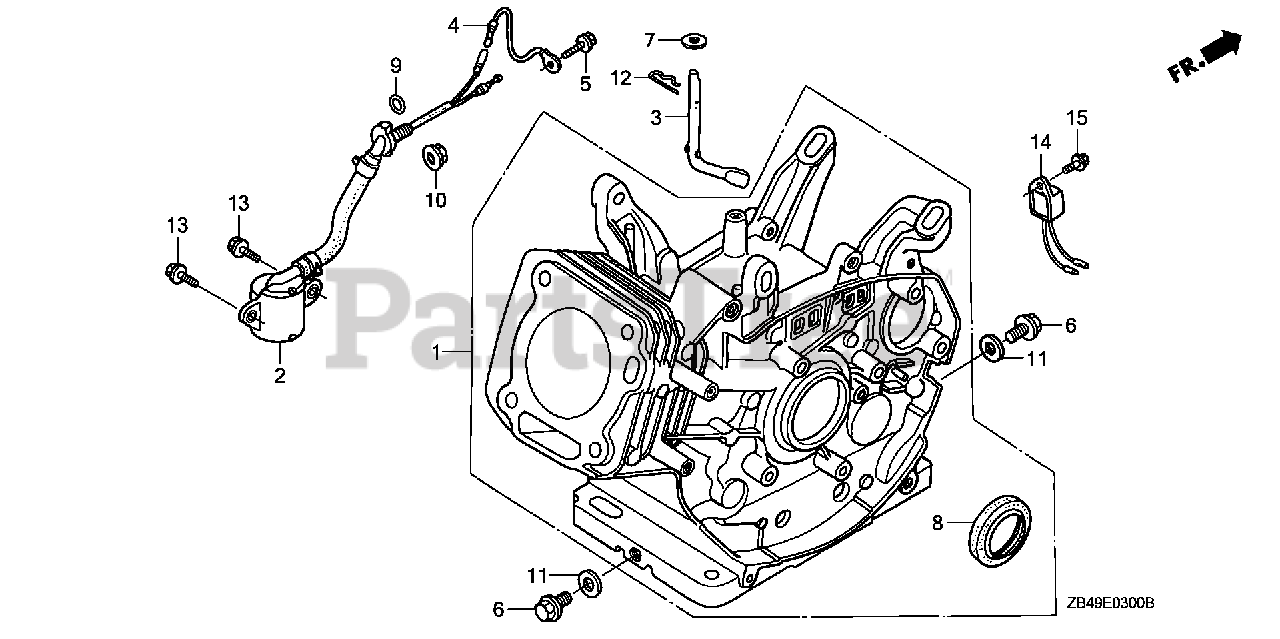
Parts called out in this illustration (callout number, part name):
1	CYLINDER ASSY. (ALERT)
2	SWITCH ASSY., OIL LEVEL
3	SHAFT, GOVERNOR ARM
6	BOLT, DRAIN PLUG (12X15)
7	WASHER (8.2X17X0.8)
8	OIL SEAL (30X46X8)
9	O-RING (14MM) (ARAI)
9	O-RING (14MM) (NOK)
10	NUT, FLANGE (10MM)
11	WASHER, DRAIN PLUG (12MM)
12	PIN, LOCK (10MM)
13	BOLT, FLANGE (6X12)
14	ALERT UNIT, OIL
15	BOLT, FLANGE (6X12) (CT200)
